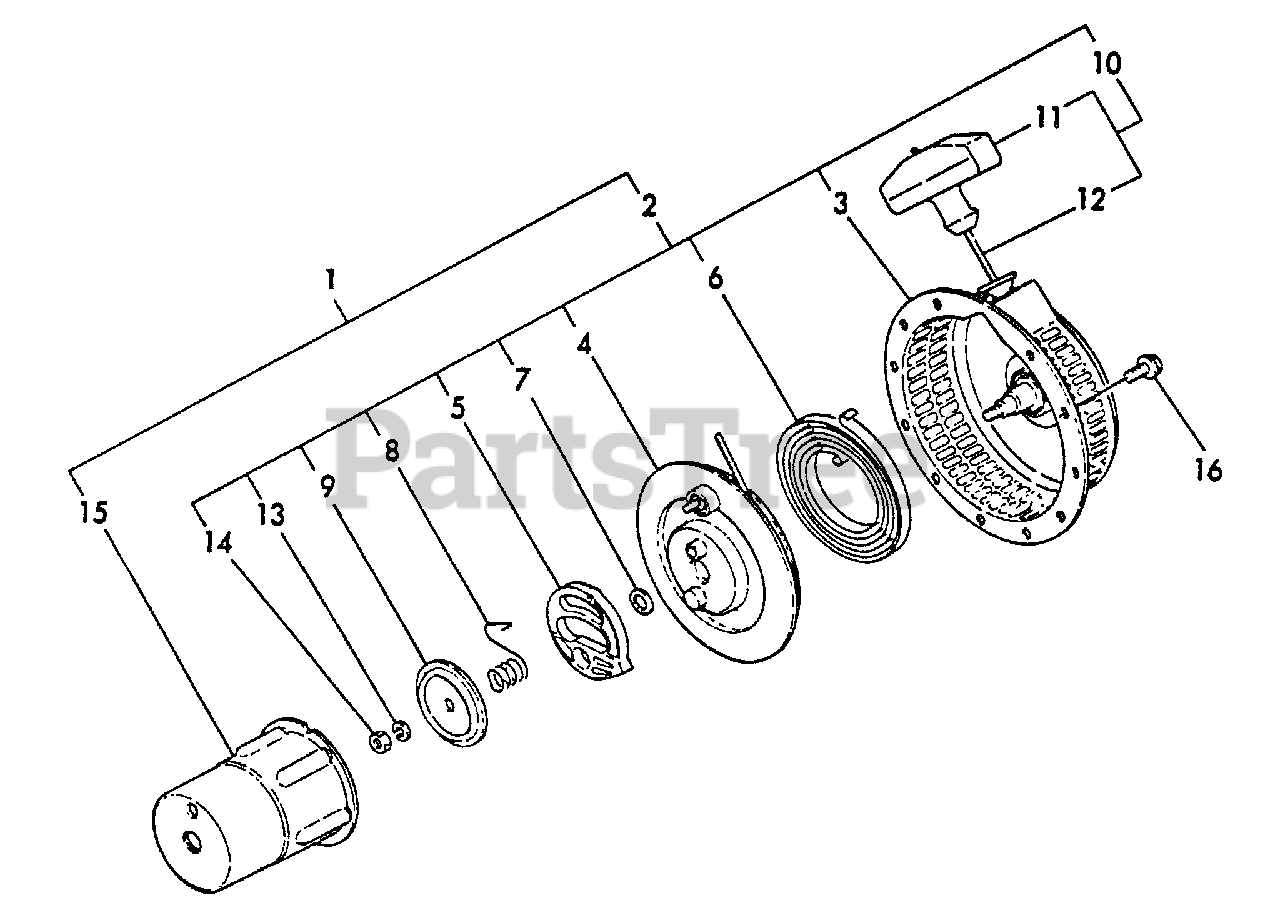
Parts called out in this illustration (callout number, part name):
1	STARTER ASSY
2	STARTER ASSY, RECOIL
3	CASE, STARTER
4	REEL
6	SPRING, SPIRAL
7	WASHER
8	SPRING, FRICTION
9	PLATE, FRICTION
10	STARTER ROPE ASSY
11	GRIP, STARTER
12	ROPE, STARTER
13	LOCKWASHER - 6
14	NUT - 6
15	PULLEY, STARTER
16	BOLT - 6×8 -- PLATED
